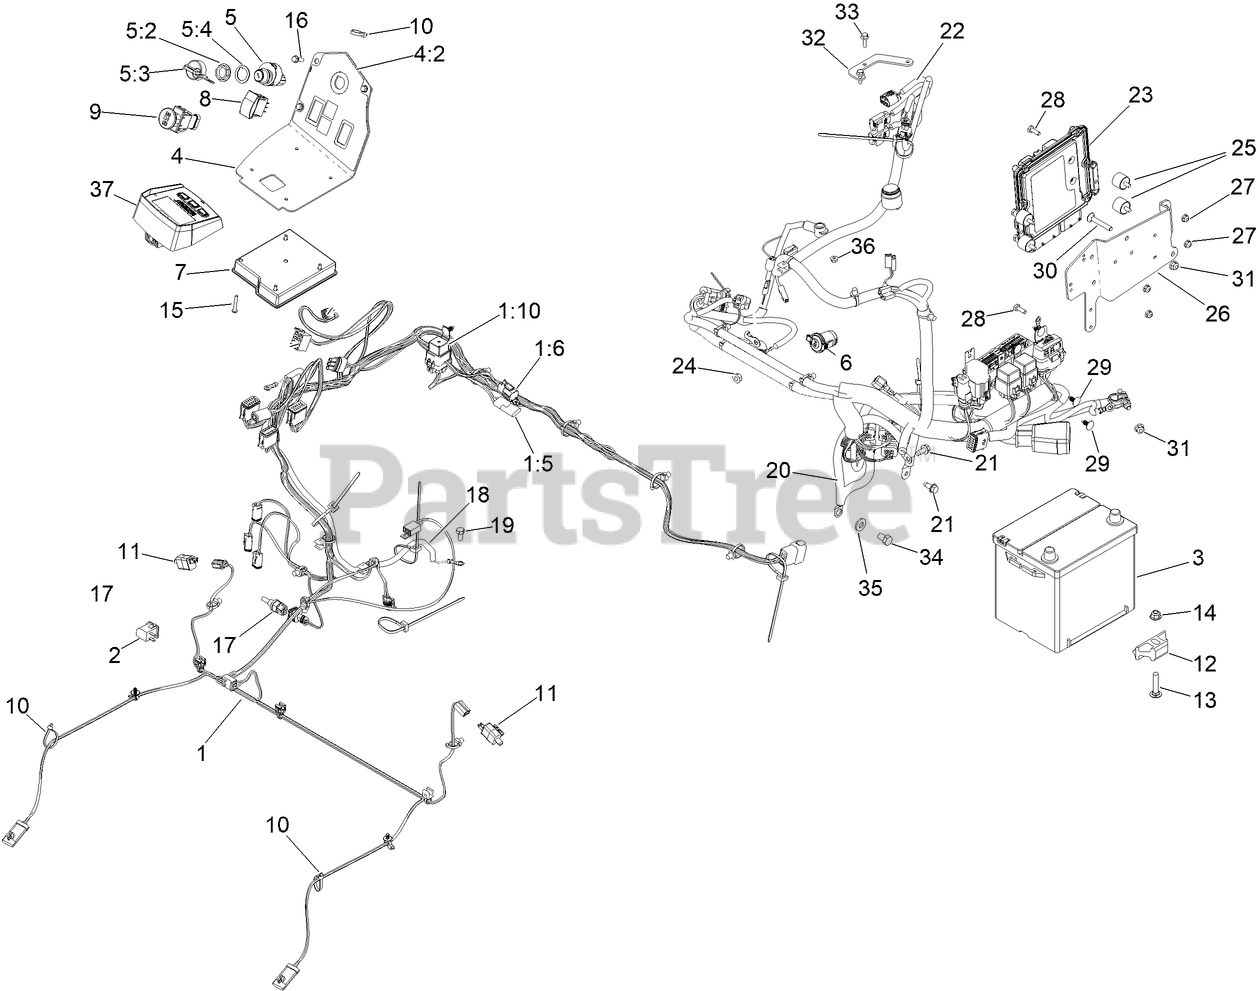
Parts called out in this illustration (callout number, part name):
1	HARNESS-WIRE, MAIN
1:5	CAP-PLUG
1:6	CAP-PLUG, 6 WAY
1:10	RELAY-MINI
2	SWITCH-BAIL
3	BATTERY-DRY
4	CONSOLE ASM
4:2	DECAL-CONSOLE
5	IGNITION SWITCH ASM
5:2	NUT-MOUNTING
5:3	IGNITION KEY SET
5:4	WASHER-BACKUP
6	PORT-POWER, 12V
7	MODULE-MCU
8	SWITCH
9	SWITCH-PTO, SEALED
10	TIE-CABLE
11	SWITCH
12	RETAINER-BATTERY
13	SCREW-CARR
14	NUT-HF, NI
15	SCREW-PPH
16	SCREW-HWH
17	SENSOR-TEMPERATURE
18	HARNESS-WIRE, JUMPER
19	SCREW-HH
20	CABLE-BATTERY
21	SCREW-HWHTF
22	HARNESS-WIRE, YANMAR
23	CONTROLLER-ENGINE
24	NUT-HF
25	MOUNT-CYLINDRICAL
26	MOUNT-CONTROL UNIT, ENGINE
27	NUT-HF
28	SCREW-HH
29	PLUG-PLASTIC
30	BOLT-CARR
31	NUT-HF, NI
32	BRACKET-WIRING, ENGINE
33	SCREW-HHF
34	SCREW-HH
35	WASHER-BELLEVILLE
36	NUT-HF
37	MODULE-HORIZON
